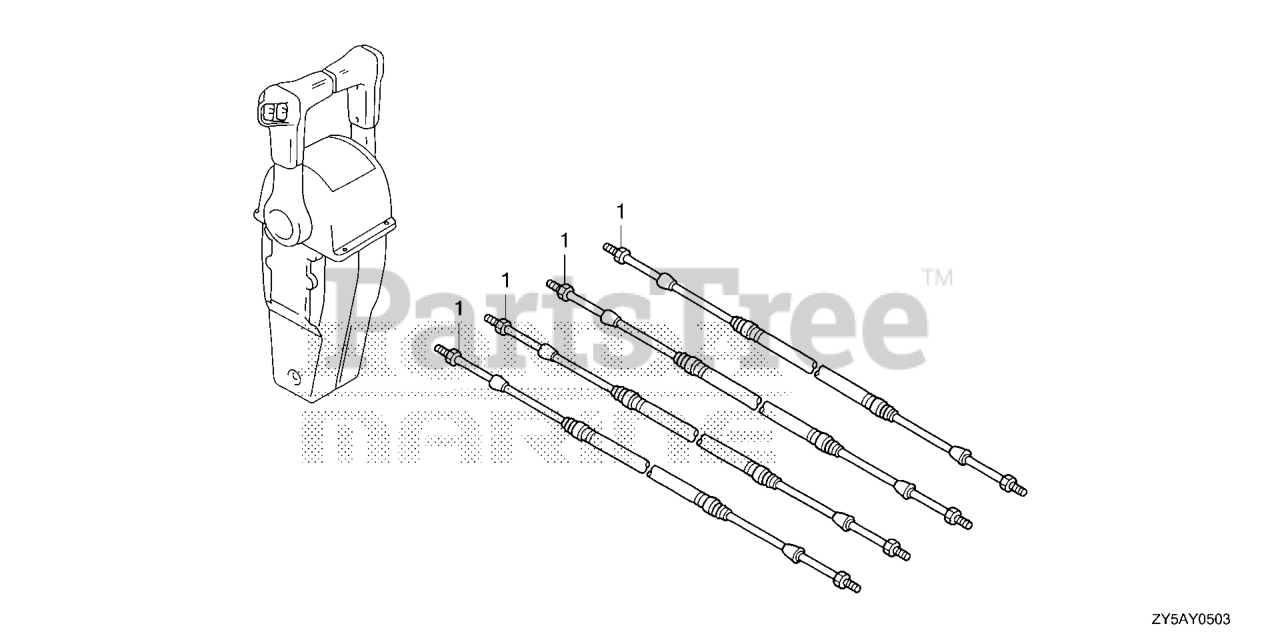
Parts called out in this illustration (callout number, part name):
1	CABLE ASSY., PUSH-PULL (33HPC-5FT)
1	CABLE ASSY., PUSH-PULL (33HPC-6FT)
1	CABLE ASSY., PUSH-PULL (33HPC-7FT)
1	CABLE ASSY., PUSH-PULL (33HPC-8FT)
1	CABLE ASSY., PUSH-PULL (33HPC-9FT)
1	CABLE ASSY., PUSH-PULL (33HPC-10FT)
1	CABLE ASSY., PUSH-PULL (33HPC-11FT)
1	CABLE ASSY., PUSH-PULL (33HPC-12FT)
1	CABLE ASSY., PUSH-PULL (33HPC-13FT)
1	CABLE ASSY., PUSH-PULL (33HPC-14FT)
1	CABLE ASSY., PUSH-PULL (33HPC-15FT)
1	CABLE ASSY., PUSH-PULL (33HPC-16FT)
1	CABLE ASSY., PUSH-PULL (33HPC-17FT)
1	CABLE ASSY., PUSH-PULL (33HPC-18FT)
1	CABLE ASSY., PUSH-PULL (33HPC-19FT)
1	CABLE ASSY., PUSH-PULL (33HPC-20FT)
1	CABLE ASSY., PUSH-PULL (33HPC-21FT)
1	CABLE ASSY., PUSH-PULL (33HPC-22FT)
1	CABLE ASSY., PUSH-PULL (33HPC-23FT)
1	CABLE ASSY., PUSH-PULL (33HPC-24FT)
1	CABLE ASSY., PUSH-PULL (33HPC-25FT)
1	CABLE ASSY., PUSH-PULL (33HPC-26FT)
1	CABLE ASSY., PUSH-PULL (33HPC-27FT)
1	CABLE ASSY., PUSH-PULL (33HPC-28FT)
1	CABLE ASSY., PUSH-PULL (33HPC-29FT)
1	CABLE ASSY., PUSH-PULL (33HPC-30FT)
1	CABLE ASSY., PUSH-PULL (33HPC-31FT)
1	CABLE ASSY., PUSH-PULL (33HPC-32FT)
1	CABLE ASSY., PUSH-PULL (33HPC-33FT)
1	CABLE ASSY., PUSH-PULL (33HPC-34FT)
1	CABLE ASSY., PUSH-PULL (33HPC-35FT)
1	CABLE ASSY., PUSH-PULL (33HPC-36FT)
1	CABLE ASSY., PUSH-PULL (33HPC-37FT)
1	CABLE ASSY., PUSH-PULL (33HPC-38FT)
1	CABLE ASSY., PUSH-PULL (33HPC-39FT)
1	CABLE ASSY., PUSH-PULL (33HPC-40FT)
